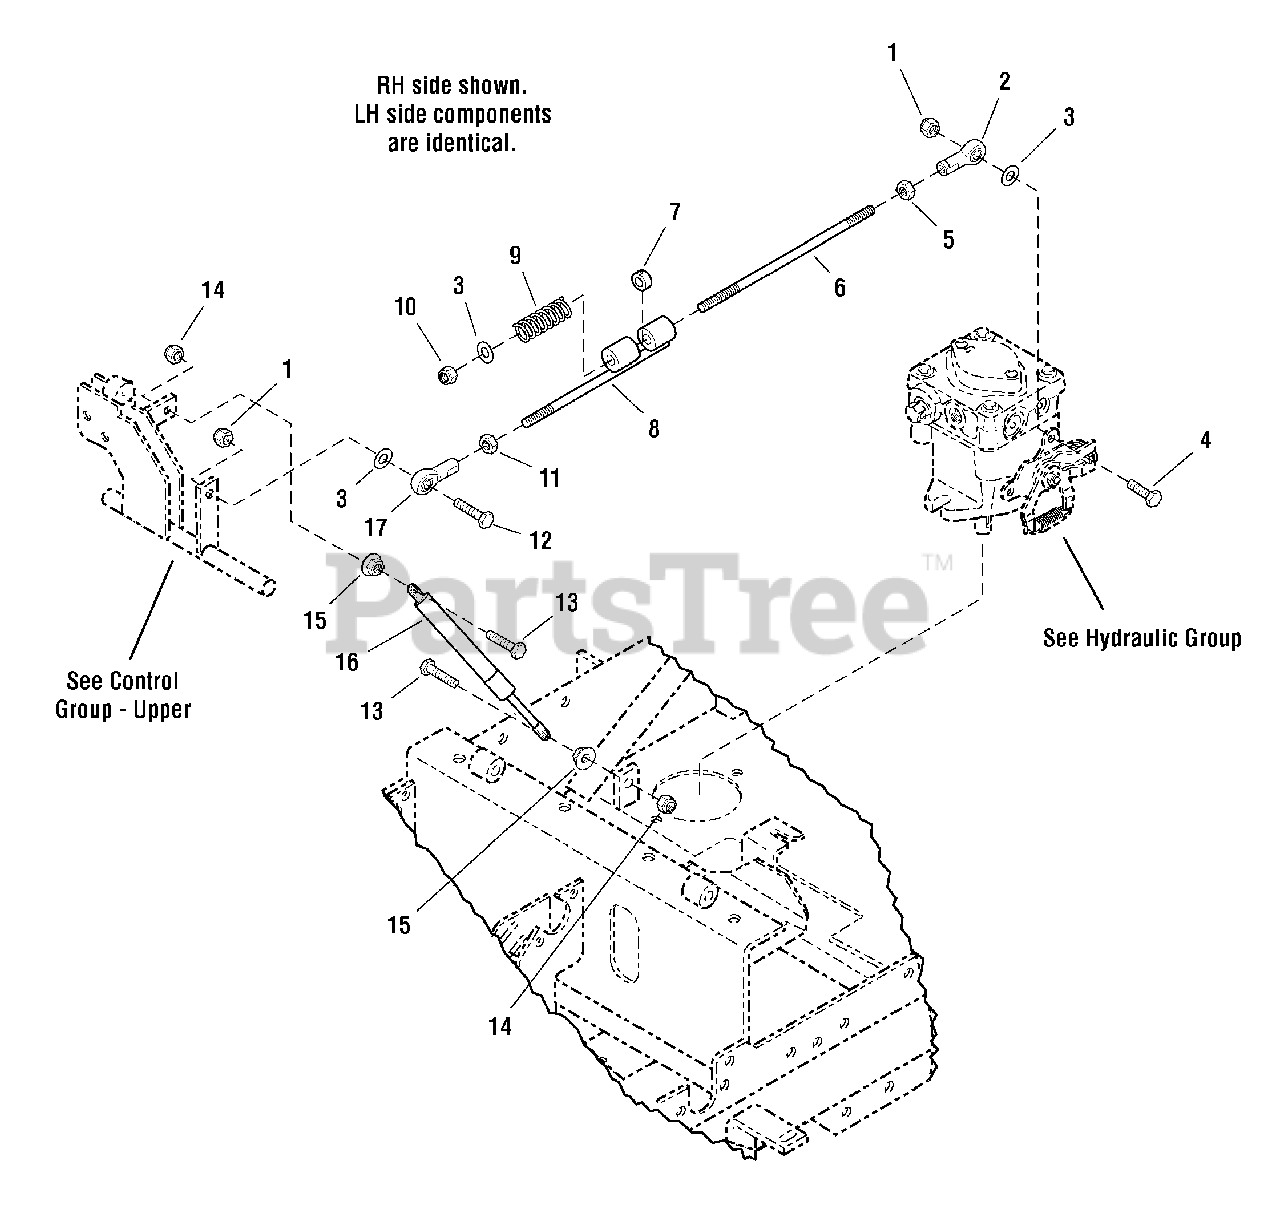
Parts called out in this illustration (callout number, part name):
1	NUT, Hex Nylon Lock, 5/16-18
2	BALL JOINT 5/16-24 LH FEMALE STAMPED STL
3	WASHER, SAE, 5/16
4	CAPSCREW, Hex Head, 5/16-18 X 1-1/8
5	NUT, Hex, 5/16-24, LH
6	ROD, 5/16 X 8.38, LH-RH, CZ
7	COLLAR, SET, 5/16
8	ROD ASSEMBLY, Slider
10	NUT, Hex Nylon Lock, 5/16-24
11	NUT, Hex, 5/16-24
12	CAPSCREW, Hex Head, 5/16-18 X 1-1/4
13	CAPSCREW, Hex Head, M8-1.25 X 35MM
14	NUT, Hex Nylon Lock, M8-1.25
15	NUT, Hex Serrated Flange, M8-1.25
16	DAMPENER
17	BALL JOINT 5/16-24 RH FEMALE STAMPED STL
